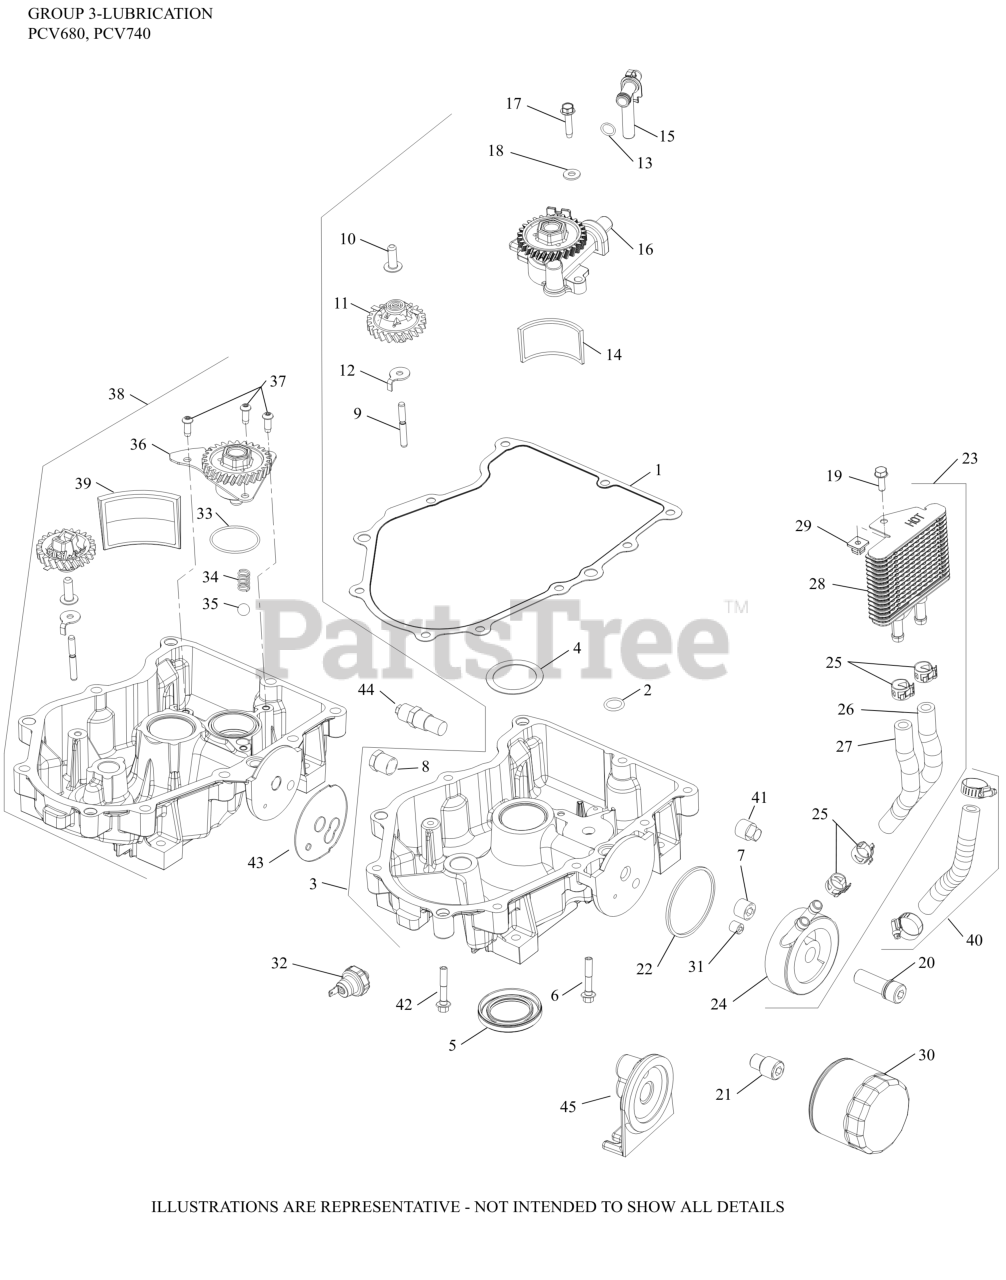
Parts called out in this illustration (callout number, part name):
1	GASKET, OIL PAN
6	SCREW, FLG M8X1.25X45
9	SHAFT, GOVERNOR GEAR
10	PIN, GOVERNOR REGULATING
11	KIT, GOVERNOR GEAR W/PIN
12	TAB, LOCKING
19	SCREW, TAP M6X1.7X18
20	NIPPLE, OIL FILTER - (#2413608S)
22	O-RING, OIL COOLER
23	COOLER, OIL & DIVERTER ASSEMBLY
24	ADAPTER, OIL FILTER (CV EFI)
25	CLAMP, HOSE LOW PROFILE
29	NUT, PLASTIC - BLACK
30	OIL FILTER
33	O-RING (1.78" DIA)
34	SPRING, COMPRESSION
35	PRESSURE RELIEF BALL
36	PUMP, OIL ASSEMBLY
37	SCREW, BUTTON HEAD
38	KIT, OIL PAN ASSEMBLY
38	PAN, ASSEMBLY OIL (SERVICE)
39	SCREEN, OIL
40	KIT, HOSE 140MM
41	PLUG, SQ HD PIPE 3/8"
42	SCREW, HEX FLANGE
